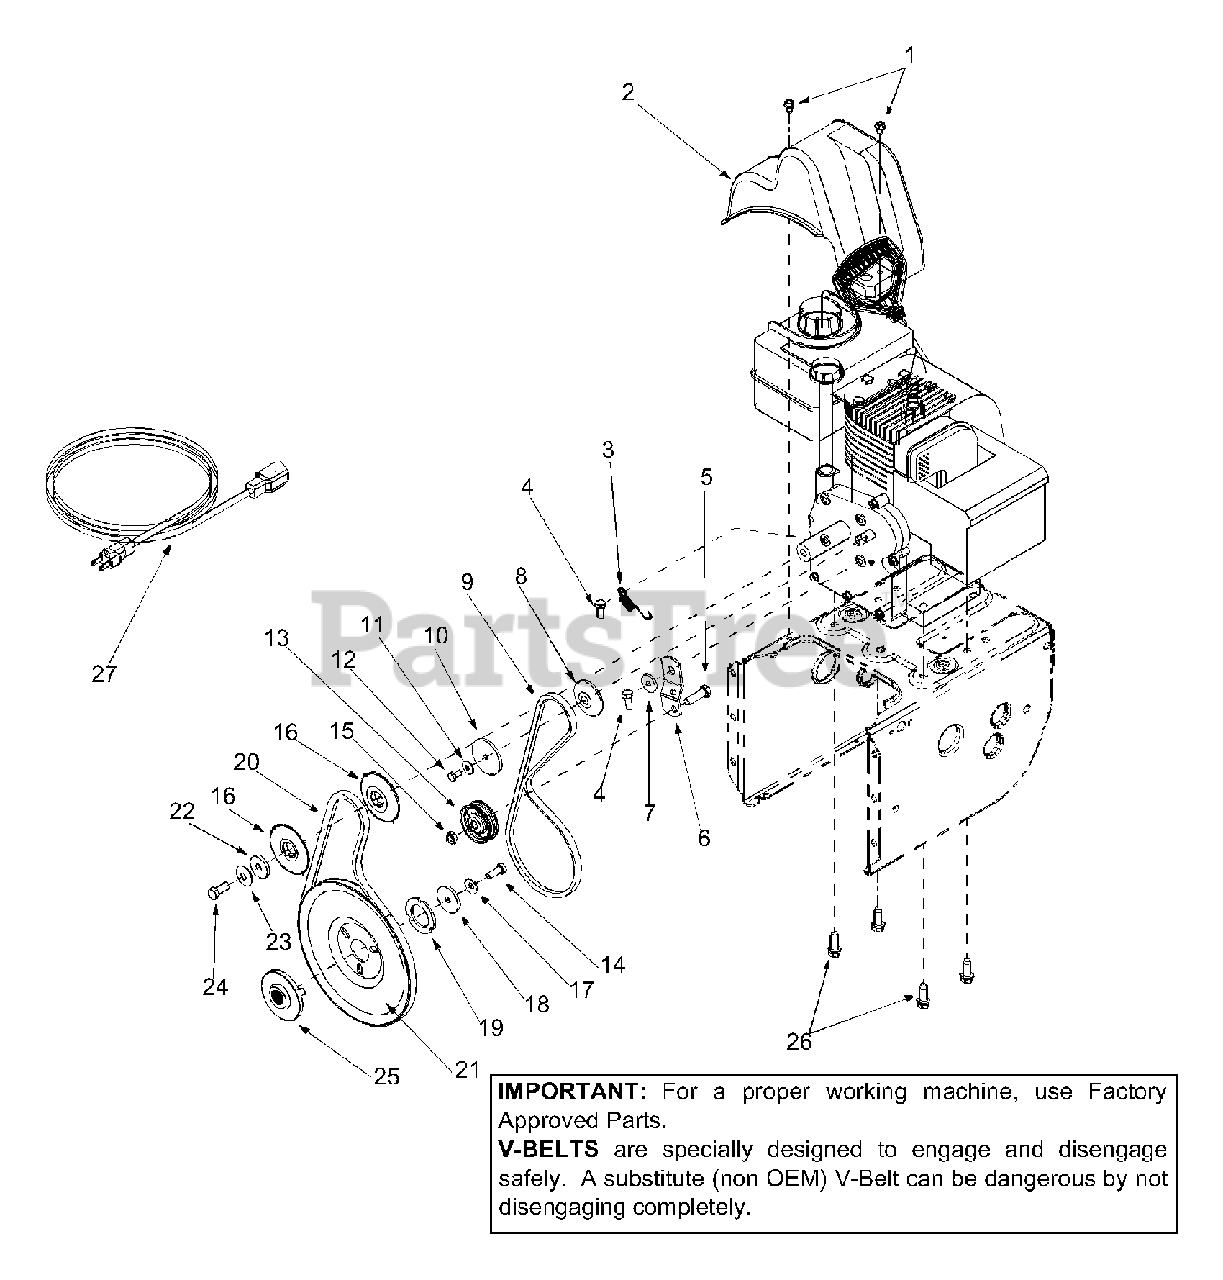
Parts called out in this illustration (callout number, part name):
1	Hex Washer Screw 1/4-20 x.5
2	Belt Cover
3	Extension Spring
4	Hex Screw 5/16-24 x .75
5	Hex Cap Screw 3/8-16 x 1.25
8	Pulley Half
9	V-Belt
10	Pulley Half
11	Bell Washer
12	Hex Cap Screw 1/4-28 x .50
13	Flat Idler
14	Lock Cap Screw 5/16-24
15	Lock Jam Nut 3/8-16
16	Pulley Half
17	Bell Washer
18	Flat Washer
19	Washer
20	Belt
21	Auger Pulley
22	Flat Washer
23	Bell Washer
24	Hex Cap Screw 3/8-24
25	Pulley
26	Hex Washer Screw 3/8-16 x 1.0
27	Extension Cord
